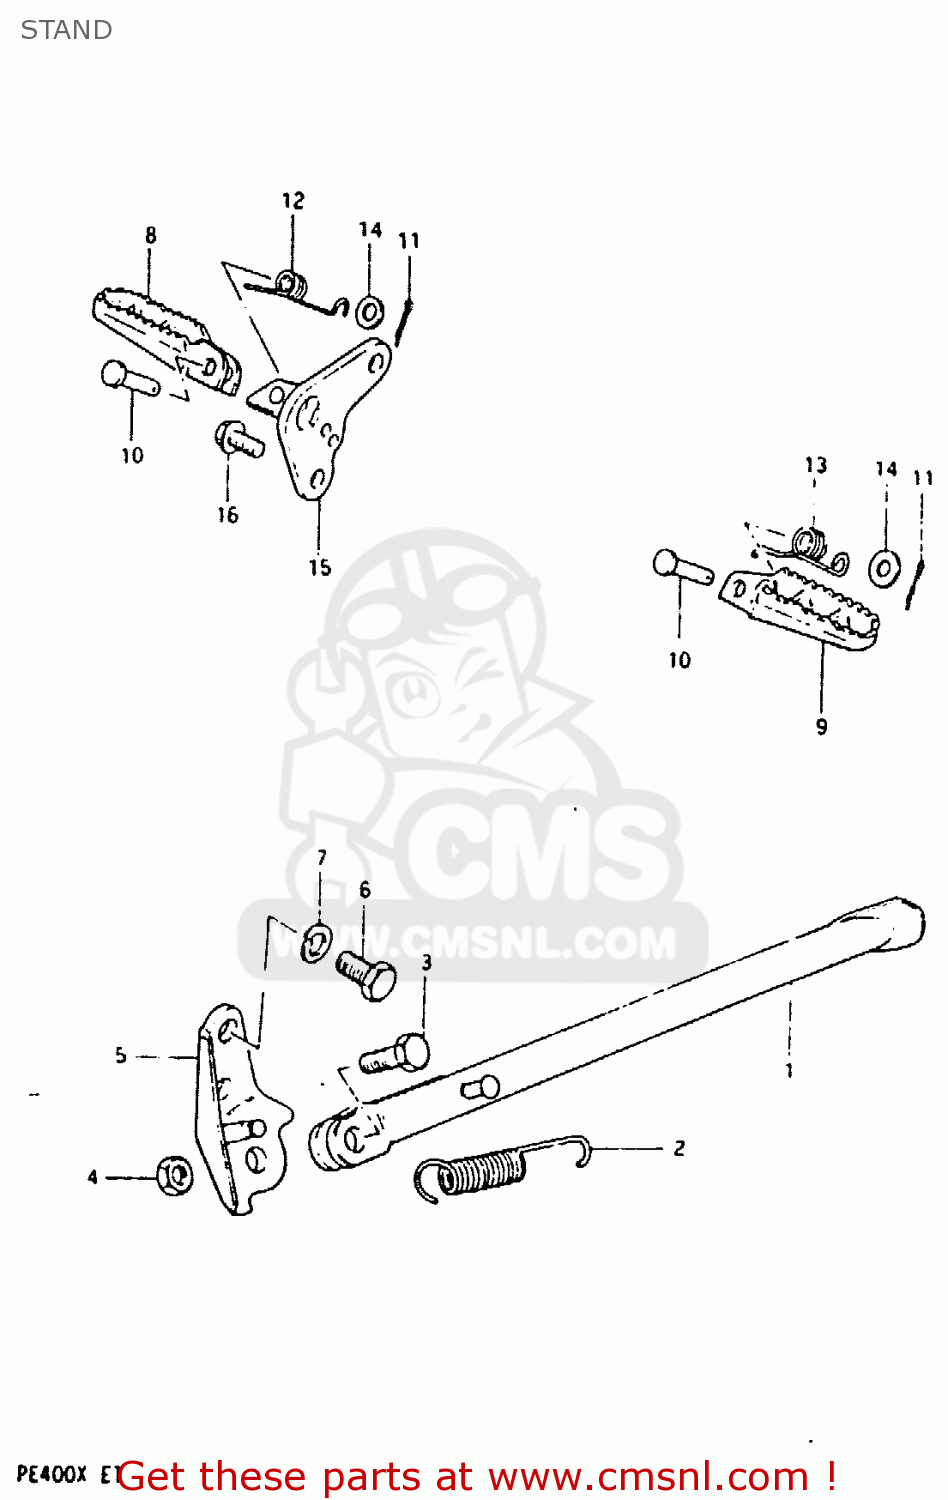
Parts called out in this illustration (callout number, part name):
1	STAND,PROP
2	SPRING
3	BOLT(10X30)
4	NUT
5	BRACKET,PROP STAND
6	BOLT(10X19)
7	LOCK WASHER
8	RUBBER,FRONT FOOTREST
9	FOOTREST
10	PIN
11	PIN 20X20
12	SPRING
13	SPRING
14	WASHER
15	HOLDER,FRONT FOOTREST,RIGHT
16	BOLT(10X20)
